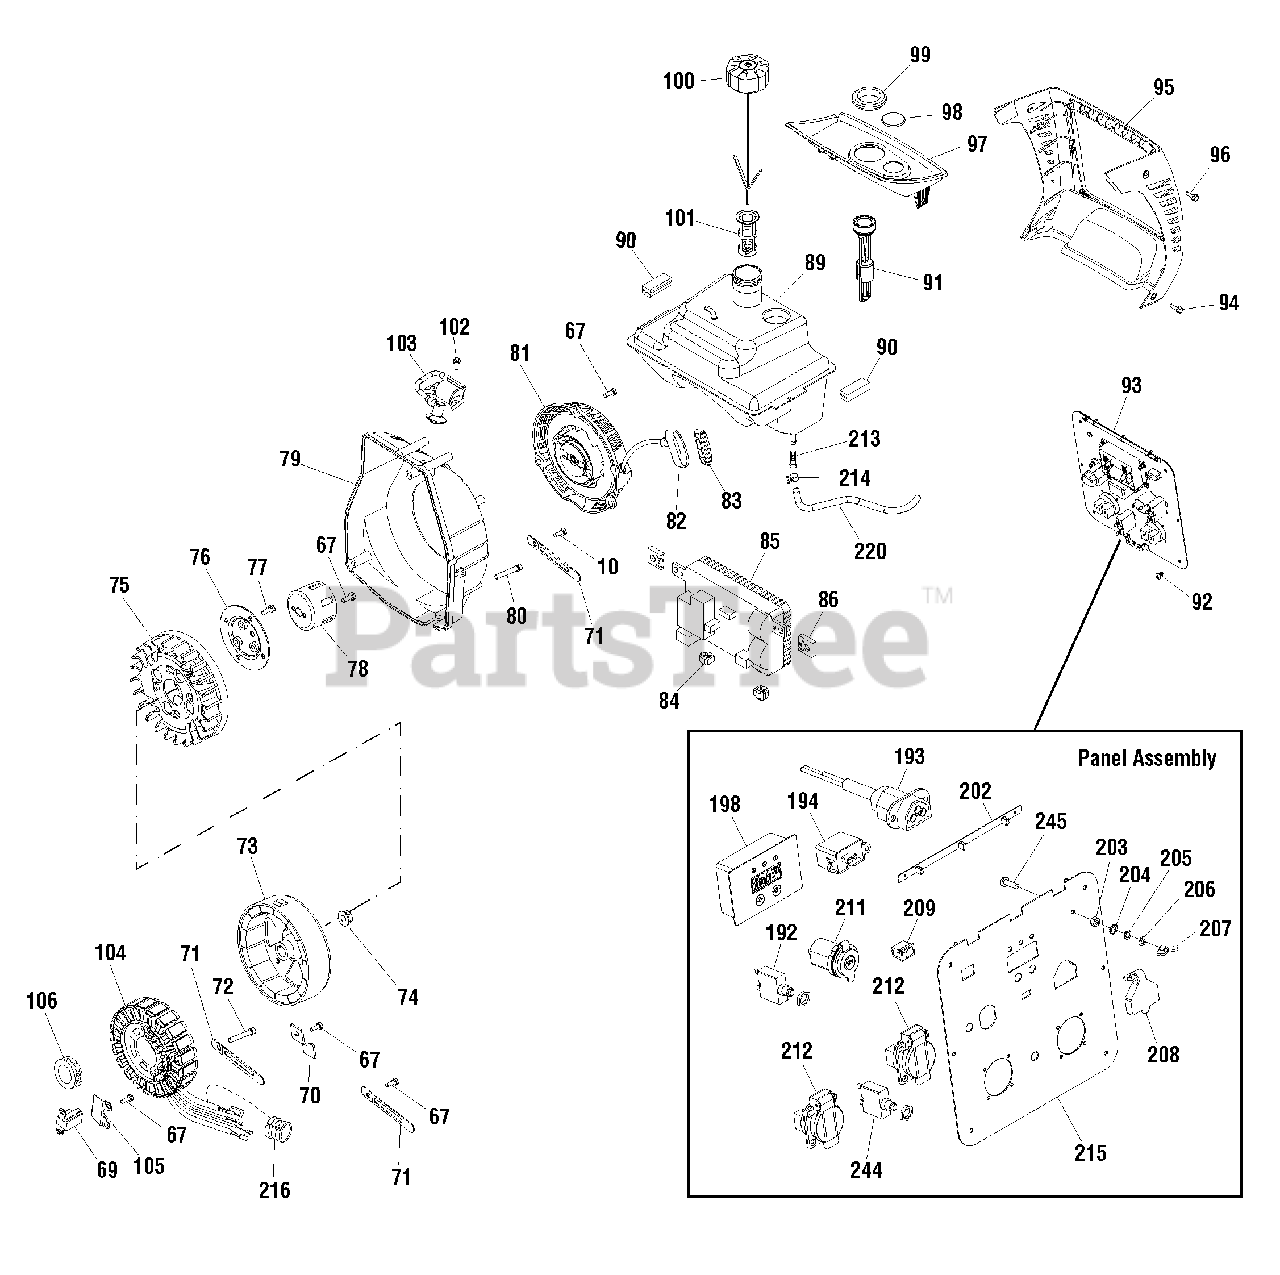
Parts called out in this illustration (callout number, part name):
10	SCREW
67	BOLT-M6 x 12
69	TRIGGER-IGNITION
70	BRACKET
71	BRACKET
72	SCREW-M6 x 60
74	NUT, FLANGE M14
76	TERMINAL
77	BOLT-M6 x 16
79	COVER-FAN
80	BOLT-M6 x 55
81	STARTER-REWIND
82	GRIP
83	INSERT-GRIP
84	MOUNT-VIBRATION
86	MOUNT-VIBRATION
90	MOUNT-VIBRATION
92	SCREW
93	PANEL-CONTROL
94	SCREW-M5 x 30
96	SCREW-M6 x 56
101	FILTER-FILLER NECK
102	SCREW
103	COIL-IGNITION
105	BRACKET
106	SEAL-OIL
192	BREAKER-CIRCUIT
193	PORT-PARALLEL
214	CLAMP
215	PANEL-CONTROL
216	COVER-RUBBER
244	BREAKER-CIRCUIT
